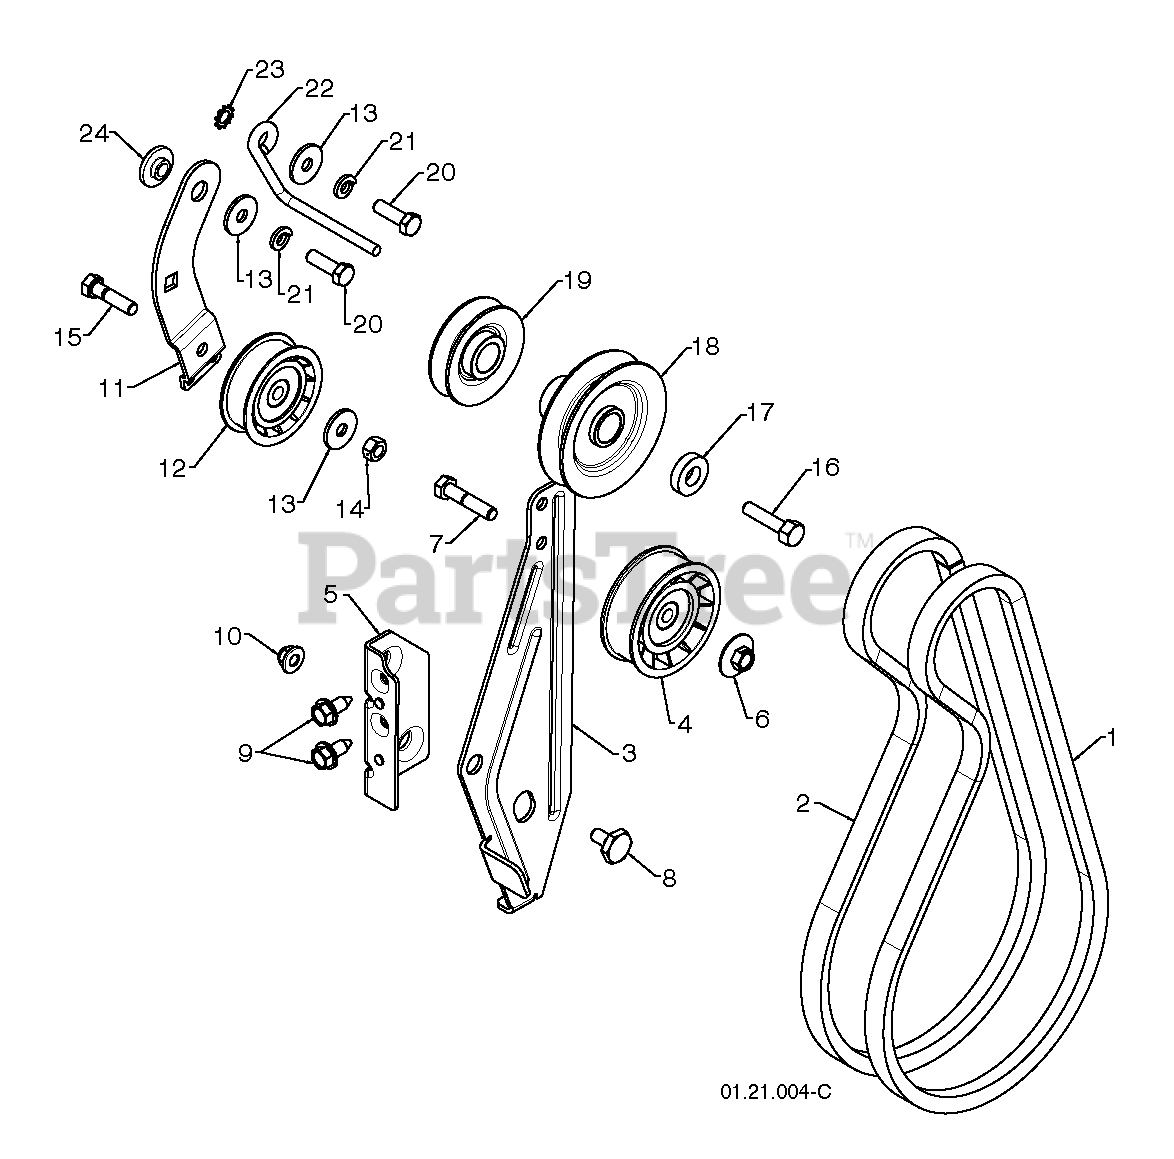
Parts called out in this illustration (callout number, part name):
1	BELT-V.IMPELLER.HS
2	V-BELT.TRACTION
3	RP ARM.IDLER.BRAKE
4	PULLEY.IDLER.W/SPACER.
5	RP BRACKET.IDLER
6	NUT.FLANGE.HEX.5/16X18.BLACK
7	HEX BOLT
8	BOLT.SHOULDER.1/2X12
9	BOLT.HEX.HD.WASHER.5/16-18X.75
10	NUT, LOCK 5/16-18
11	ARM, IDLER
12	PULLEY.W/SPACER.2.25
13	STEEL WASHER
14	NUT.71038.31-18.HEX.NYLOCK
15	BOLT.5/16-18X1-1/4 FULL.THREAD
16	SCREW, HEX HD 3/8-24 X 1-3/8
17	WASHER, FLAT 3/8
18	PULLEY.ENG.IMPELLER.
19	PULLEY.ENG.TRACTION
21	LOCKWASHER
22	GUIDE BELT
23	WASHER EXT TOOTH LOCK 5/16
24	BUSHING, IDLER PIVOT
